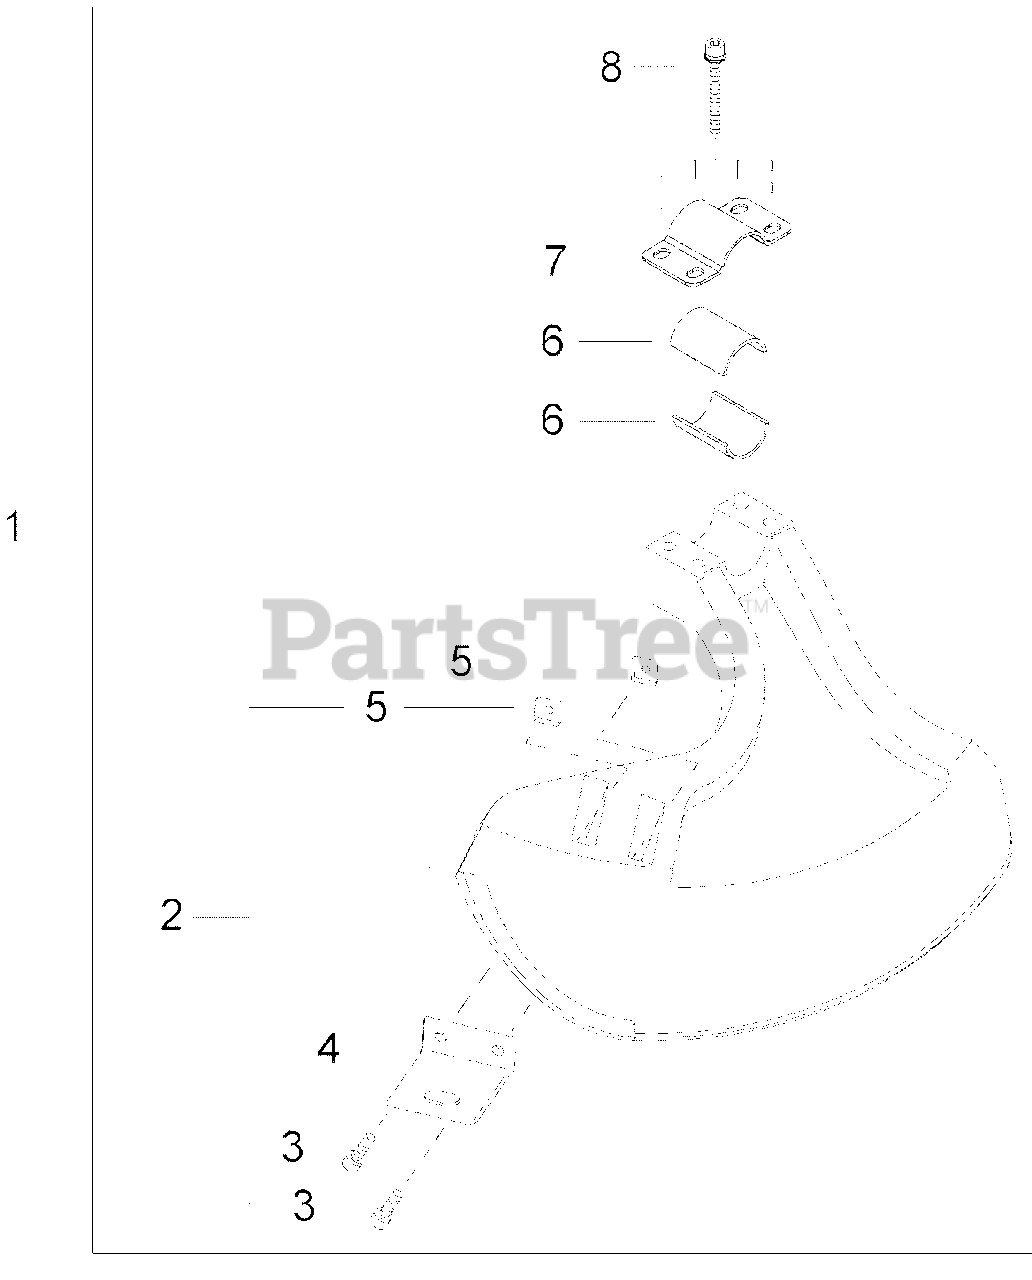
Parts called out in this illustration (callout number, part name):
1	DEBRIS SHIELD KIT
2	DEBRIS SHIELD ASSY
3	SCREW - 5X16
4	KNIFE, TRIMMER LINE
5	NUT - 5
6	SPACER
7	CLAMP - UPPER
8	SCREW - 5X45
